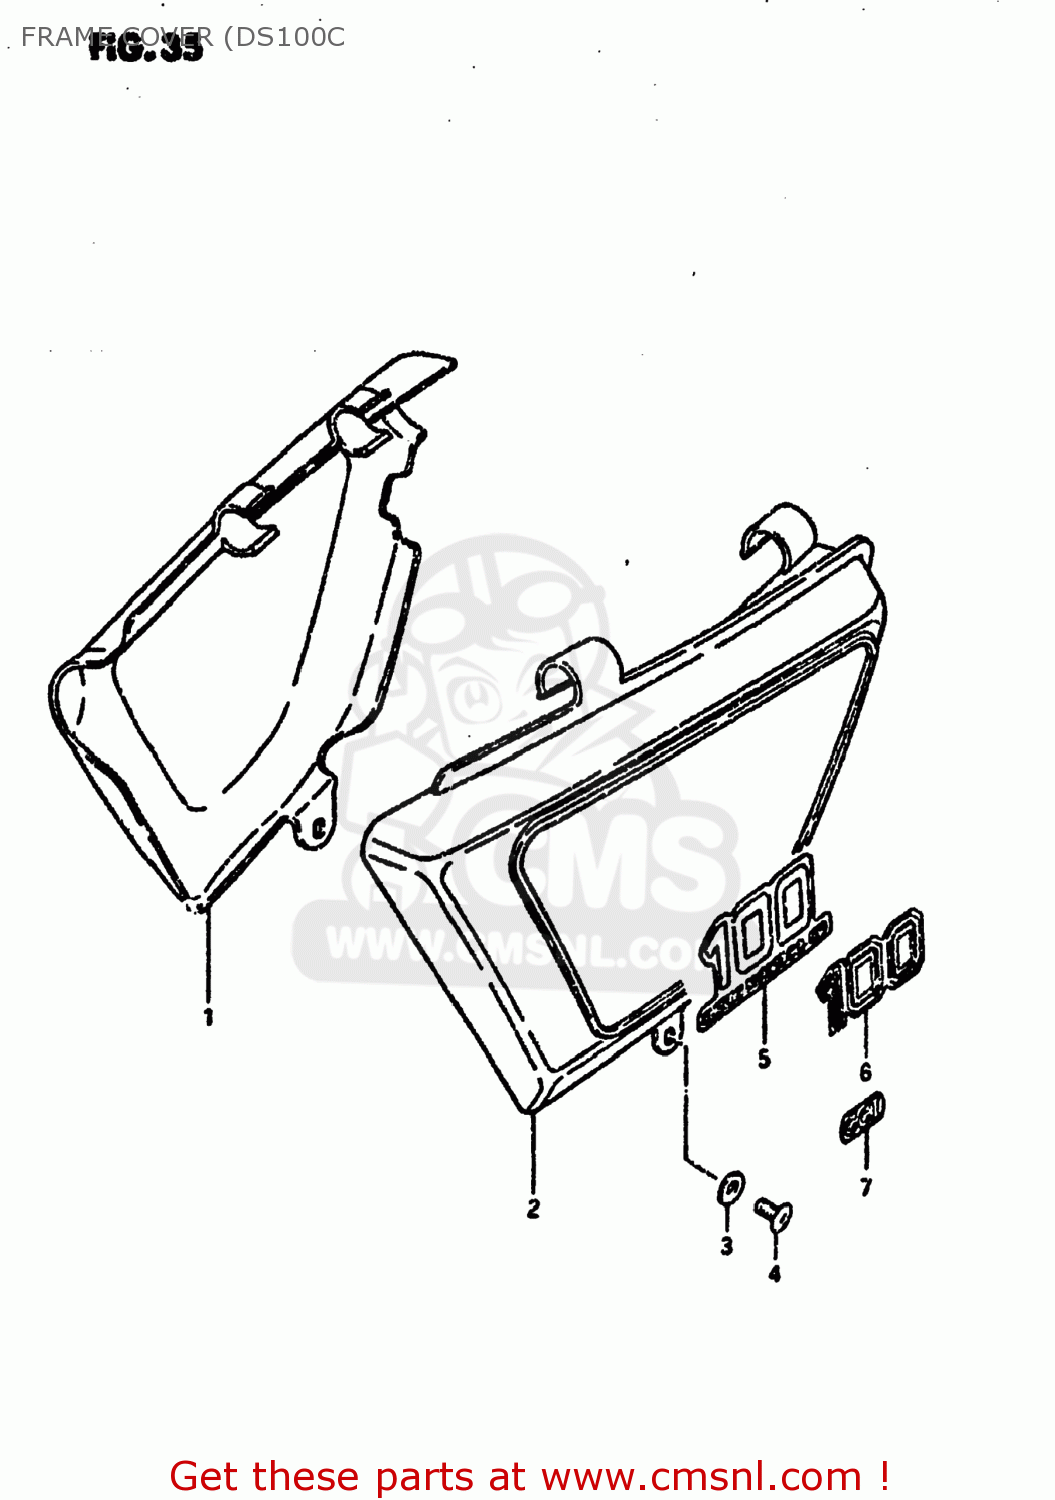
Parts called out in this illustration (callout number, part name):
1	COVER,FRAME,RIGHT
2	COVER,FRAME,LEFT
3	WASHER
4	SCREW 6X12
5	EMBLEM
6	EMBLEM
7	EMBLEM,CCIS
